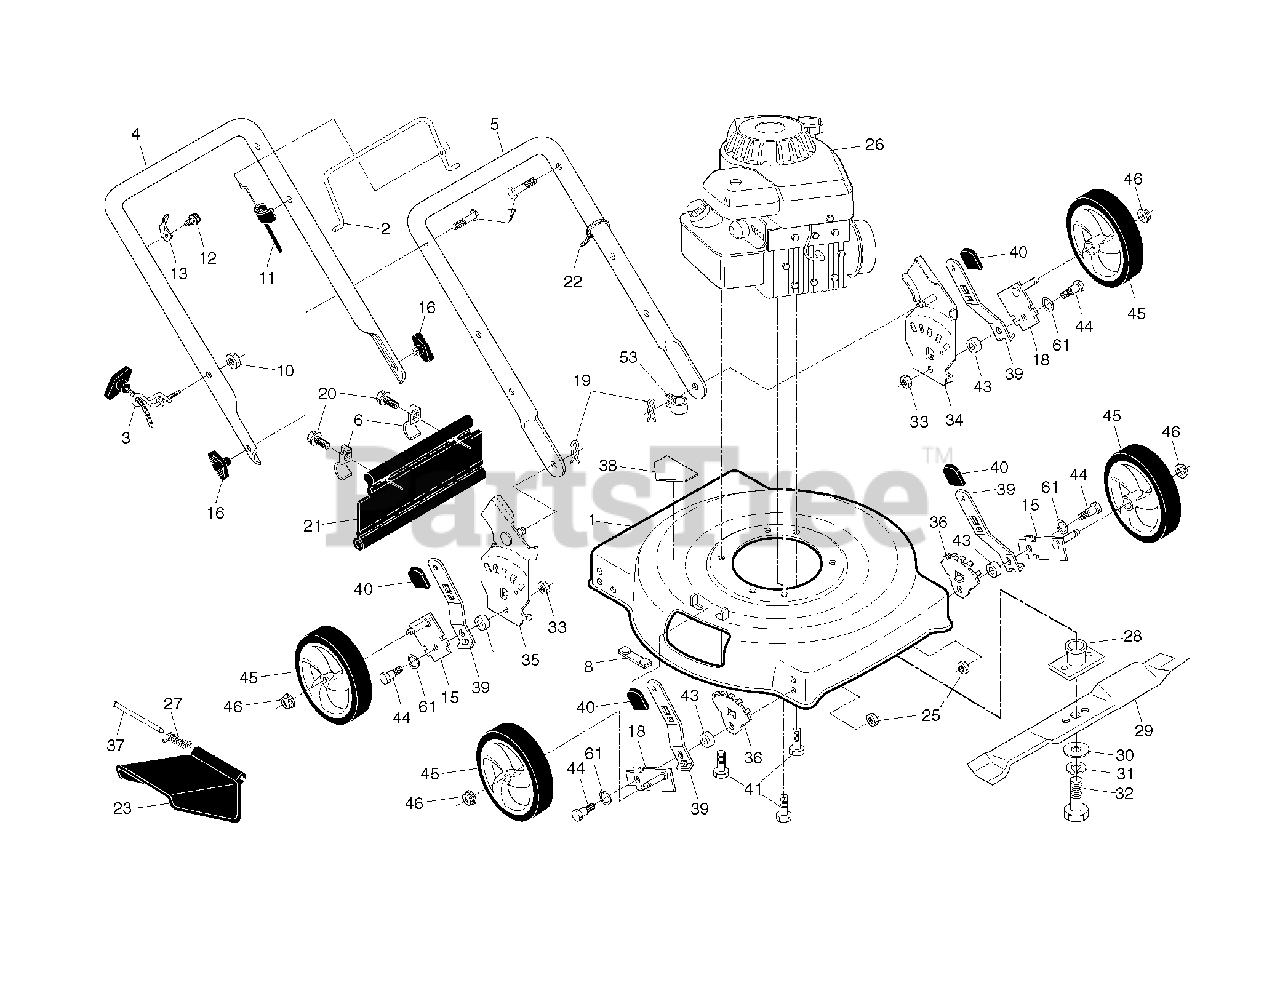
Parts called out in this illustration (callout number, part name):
1	HOUSING.22.ECON.PUSH.BLACK.WAL
2	BAIL.CONT.D.STRAIGHT.PUSH.BLK
3	GUIDE.ROPE.STD.BLK.ZIN
4	HANDLE.UPPER.ECONOMY.BLACK
5	HANDLE.LOWER.D-STRAIT.BLACK
6	BRACKET.SKIRT.BZP
7	BOLT, HANDLE 5/16-18X1.75
8	CLIP. CLOSEOUT
10	NUT
11	CABLE.MZR.RATO.22"LOW.
13	BRACKET.UPSTOP.RT
15	AXLE ARM ASSY FRONT LH
16	KNOB.WING.PLASTIC.BLACK
18	AXLE ARM ASSY FRONT RH
19	HAIRPIN COTTER
20	TAPPING SCREW
21	SKIRT.REAR.22RD/SD.FO/VE
22	TIE GUIDE
23	GUARD.DISCHARGE.22".
25	NUT.FLANGE.HEX.5/16X18.BLACK
27	SPRING.HINGE
28	BLADE ADAPTOR
29	BLADE.22.MULCH.STANDARD
30	WASHER,HARDEN
32	SCREW, HEX HD 3/8-24 X 1-3/8
33	NUT.CENTERLOCK.5/16-
34	BRKT.ASM.COM.HND/ADJ.LT.BLACK
35	BRACKET.ASM.COM.HND/ADJ.RT.BLA
36	WHEEL ADJ BRACKET FRONT
37	HINGE ROD
38	No Step Decal
39	SELECTOR SPRING, FRONT
41	BOLT 3/8-16X1-1/8
43	SPACER.HEIGHT.ADJUSTER
44	SHOULDER BOLT 5/16-18
45	WHEEL.7X1.5.DMD.GS.3SPK.PGRN.1
46	NUT.HEX.FLANGE.3/8-16.LOCKNUT
61	WASHER.CURVED.CYLINDRICAL
